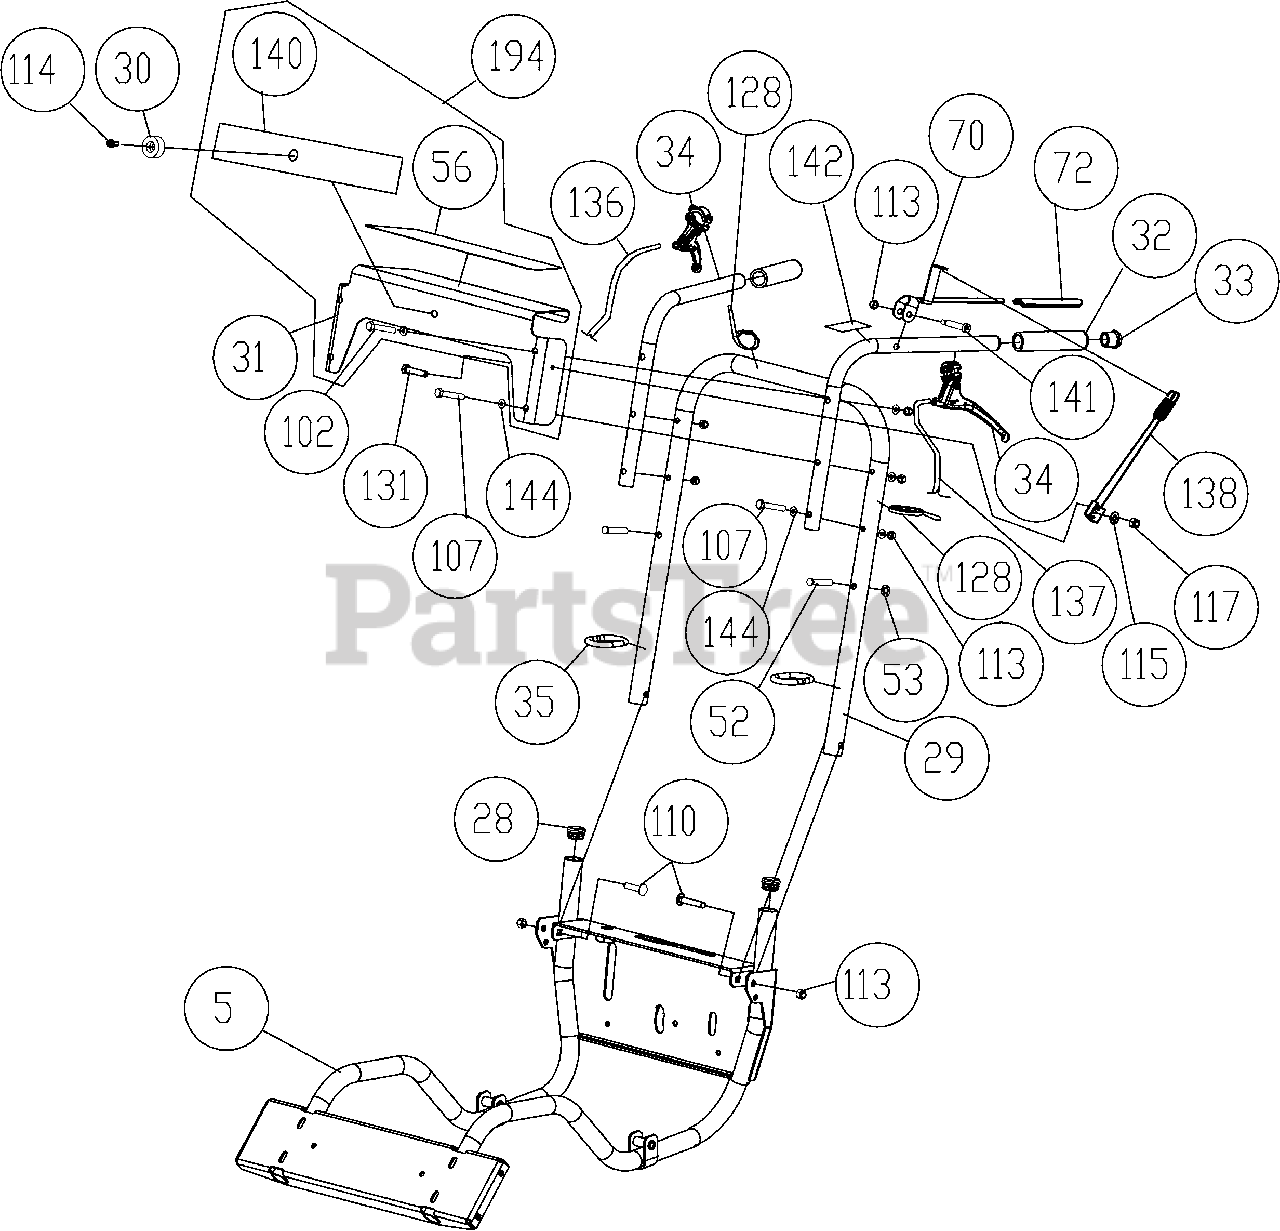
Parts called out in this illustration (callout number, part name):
5	FRAME SUPPORT OS900SP WA
28	PLUG TUBE INSERT 1.25 OD
29	HANDLE FOLDING OS900SP
30	BUMPER RECESS
31	BRACKET CONSOLE OS900SP
32	GRIP HANDLE
33	PLUG TUBE INSERT 1" OD
34	CONTROL MAGURA OS900SP
35	LOOP FOLDING HANDLE
52	PIN CLEVIS 3/8 X 2.125
53	RETAINER 3/8" BOLT PUSH NUT
56	LABEL INSTRUCTION OS900SP
70	LEVER CLUTCH/SEED DROP
72	GRIP LEVER 0.125" X 1" X 5" ORANGE
102	SCREWCAP 3/8"-16 X 1 3/4" HCS ZP
107	SCREWCAP 3/8"-16 X 3" HCS ZP
110	BOLT CARRIAGE 3/8"-16 X 2" ZP
113	LOCK NUT 3/8-16
114	SCREW SELF TAP 1/4"-20 X 5/8" HWH TYPE F
115	WASHER 1/4" SAE
117	LOCK NUT 1/4-20
131	SCREWCAP 1/4"-20 X 1" HCS ZP
136	CABLE SPEED CONTROL RT
137	CABLE SPEED CONTROL LFT
138	CABLE CLUTCH SEEDING CONTROL
140	LABEL LOGO OS900SP
141	BOLT SHOULDER 3/8" X 1 1/4"
142	LABEL CLUTCH BLADE
144	WASHER 3/8 FC
194	BRACKET CONSOLE OS900SP W/LABELS
